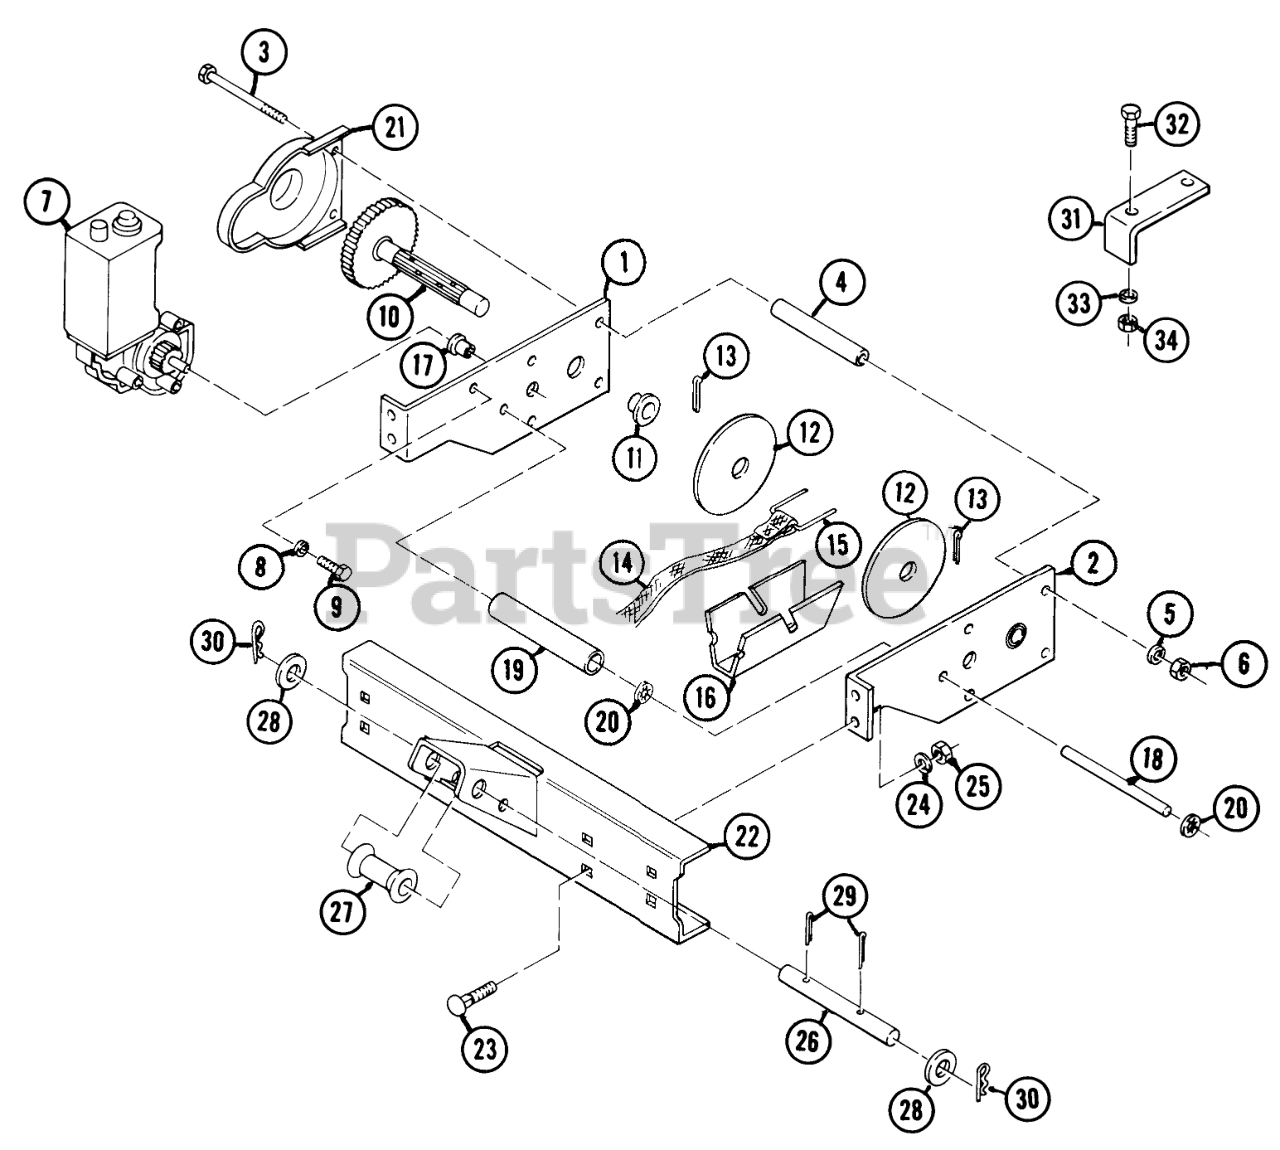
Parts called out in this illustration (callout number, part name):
3	Bolt, Hex 1/4-20 x 4 1/2
7	Motor
12	Guide Washer
28	Washer, Plain 1/2
33	Lockwasher, 1/2
